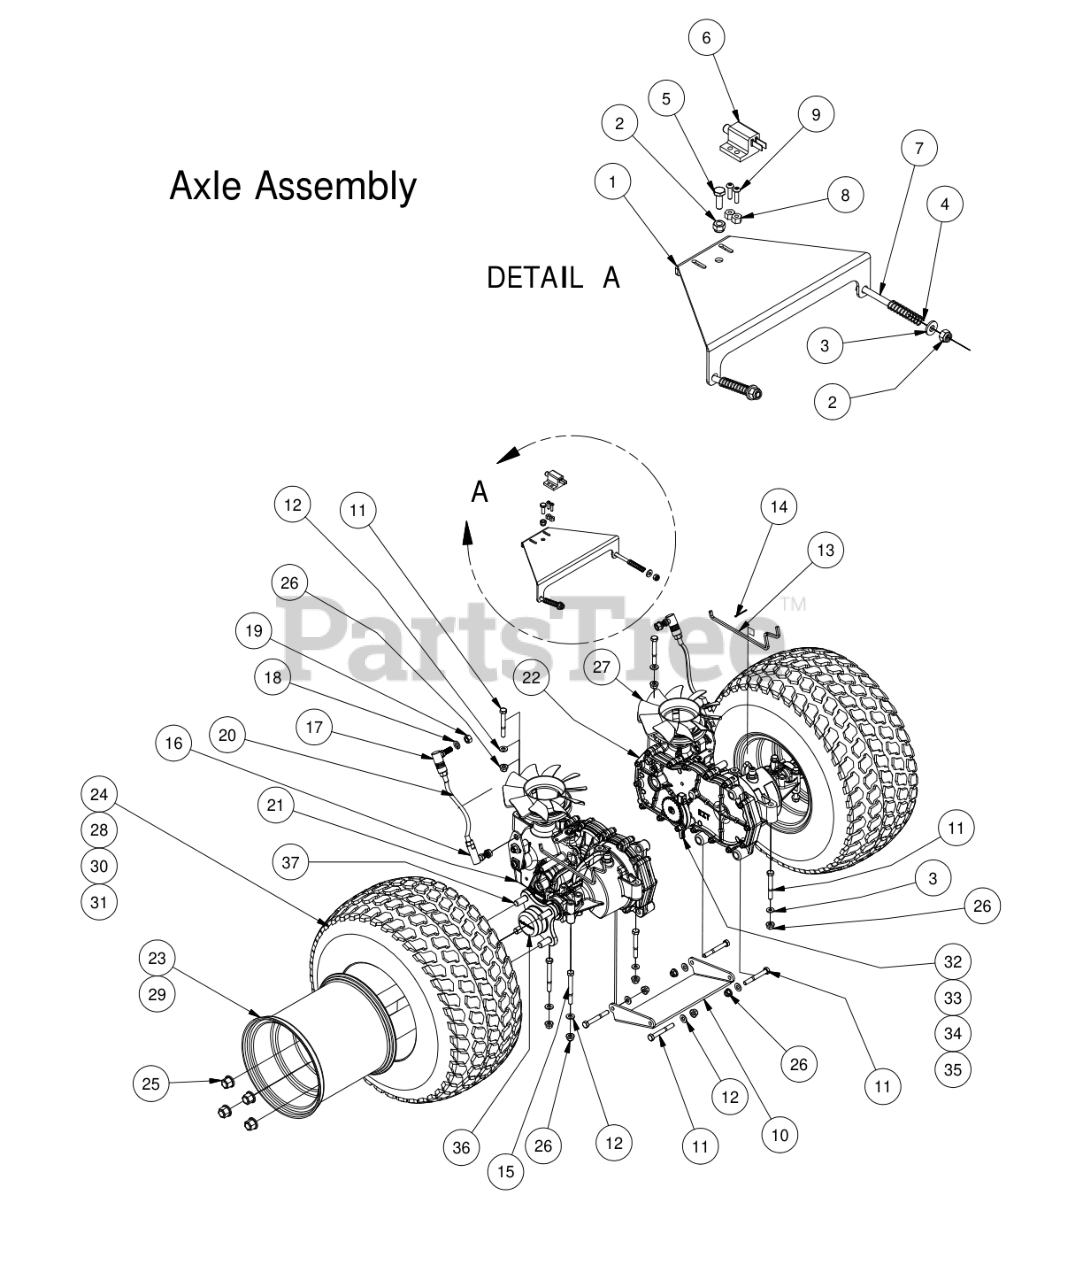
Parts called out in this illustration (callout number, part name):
1	MZ Brake Lock Bracket
2	1/4" Nylock Nut
3	1/4" Flat Washer
4	Brake Spring
5	1/4" x 3/4" Hex Bolt
6	Safety Switch
7	1/4-20 x2-1/2 Gr2 hex C/s zinc
8	10-24 Nylon Insert Locknut
9	10-24 X 5/8 BS Button Head Bolt
10	MZ Transaxle Support (Lower)
11	5/16" x 2 1/2" Bolt
12	5/16" Flat Washer
13	MZ Brake Release Bar
14	Cotter Pin-Brake bar on Mz
15	5/16" x 3" Hex Bolt
16	3/8-24 Ball Joint
17	Quick Release Ball Joint
18	3/8" Lock Washer
19	3/8" Fine Threaded Jam Nut
20	MZ/Magnum Push Rod - 2014
21	EZT- Left MZ Models
22	EZT -Right MZ Models
23	Rear rim for a 48 & 54"
24	18 x 9.50 -8 Tire Only MZ 48 &54" Deck only
25	Acorn Lug Nut
26	5/16" Nylon Flange Nut
27	MZ Fan & Pulley Kit
28	42" MZ 18x 7.50-8 tire only
29	Rear rim only 42" MZ
30	18x9.50-8 48 & 54" Deck Tire and Wheel Assembly
31	18x8.50-8/8" 42" Deck Tire and Wheel Assembly
32	MZ Brake Cog Kit
33	MZ Retainer Ring for Brake
34	MZ Brake Gear
35	MZ Brake Arm Kit
36	Mz 4 Bolt Hub Kit
37	Transaxle Wheel Studs
